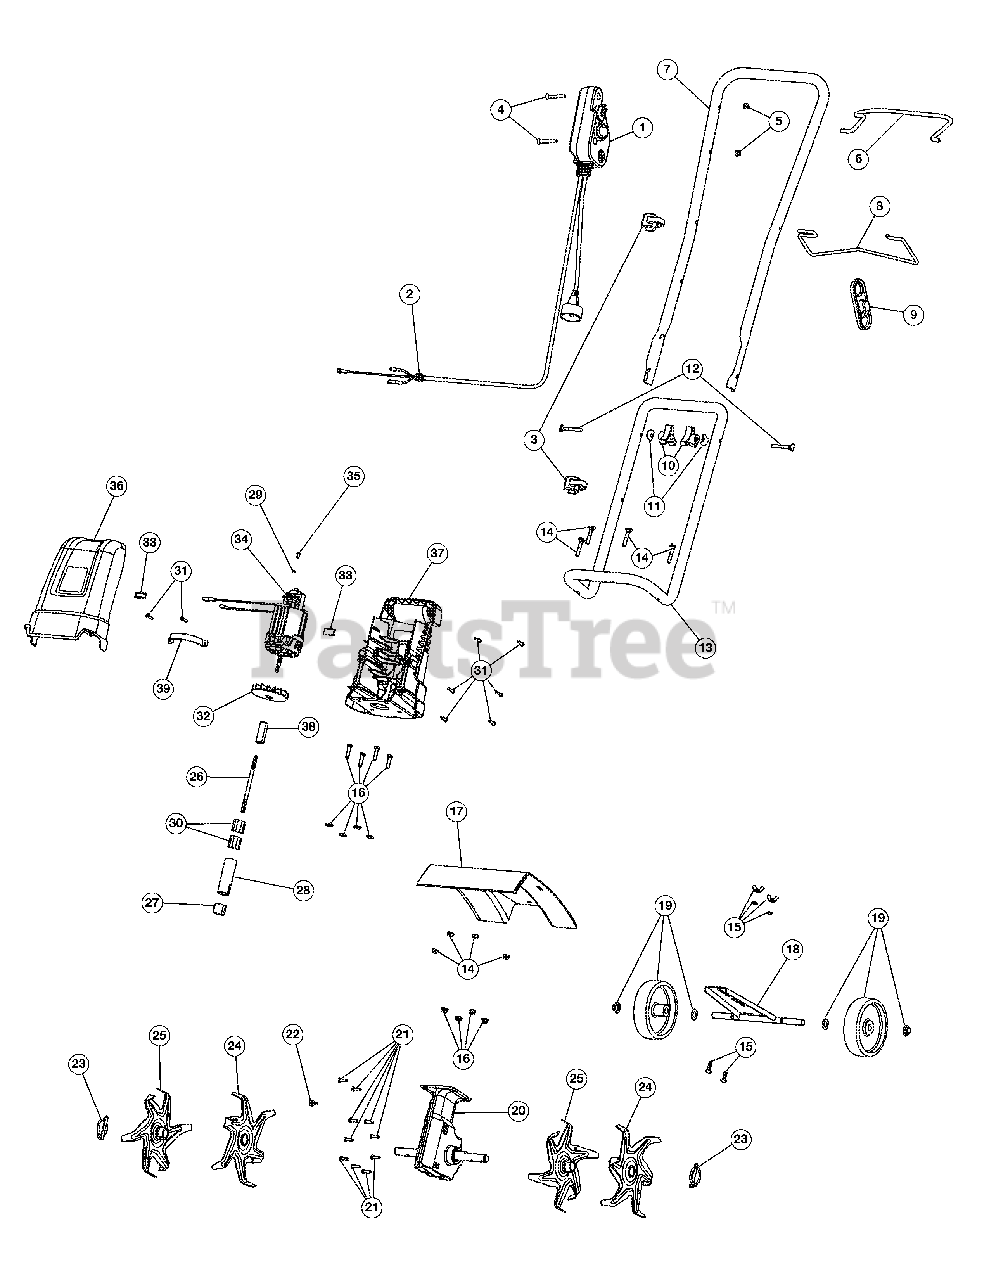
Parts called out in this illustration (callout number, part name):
1	Switch Assembly
2	Bushing
3	Cable guide
7	Upper Handle
8	Guide Bar
9	Cord Restraint
11	Washer
13	Lower Handle Bar
14	Hardware, Handle Bar Mounting (lower)
15	Wheel Bracket Mounting Hardware
16	Guard Mounting Hardware
18	Wheel Bracket Assembly
19	Wheel Assembly
20	Gear Box Assembly
22	Sleeve Retainer Bolt
23	Click Pin
24	Tine Assembly (Left Outer or Right Inner)
25	Tine Assembly (Left Inner or Right Outer)
26	Flex Shaft
27	Sleeve
28	Boom Tube
29	Lock Washer
30	Flex Tube Assembly
33	Motor Pad
34	Motor Assembly
36	Front Motor Cover
37	Rear Motor Cover
38	Motor Hub
39	Motor Strap
